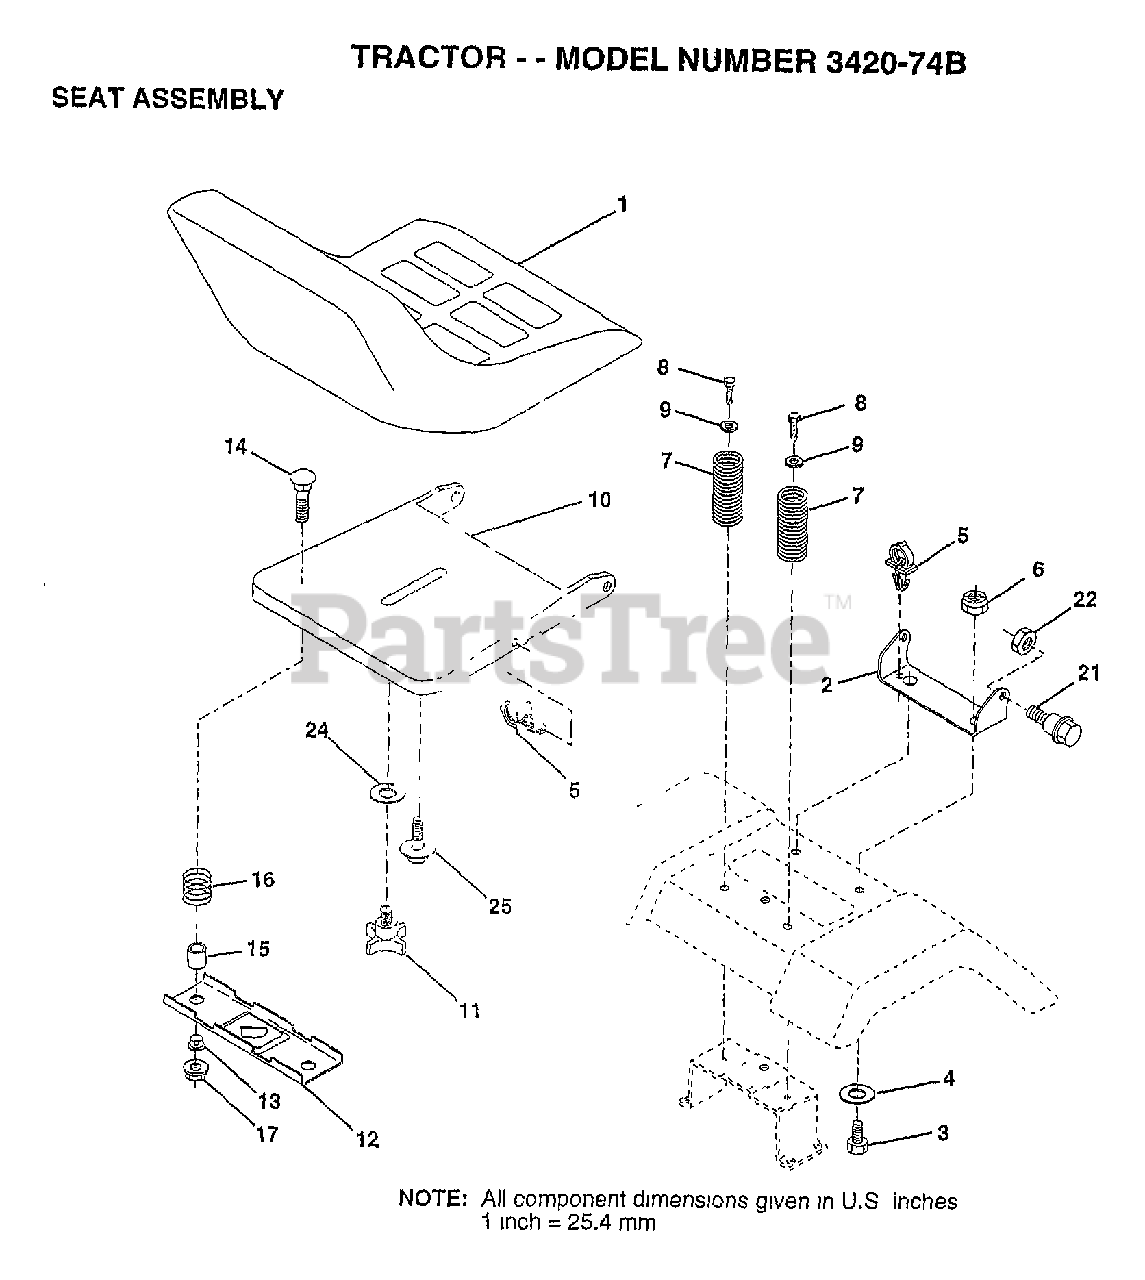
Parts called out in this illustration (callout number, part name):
2	BRACKET PVT SEAT
3	BOLT
4	WASHER PM
5	CLIP.PUSH-IN.HING
6	NUT
7	SPRING COMPRESSIO
8	SCREW GTV
9	WASHER
10	PAN-SEAT
11	"KNOB 1/2"" YT"
12	BRKT SWITCH
13	BUSHING
15	SPACER SPLIT
16	SPRING COMPRESSED
21	"BOLT,SHOULDER"
24	WASHER
25	"BOLT,SHOULDER"
